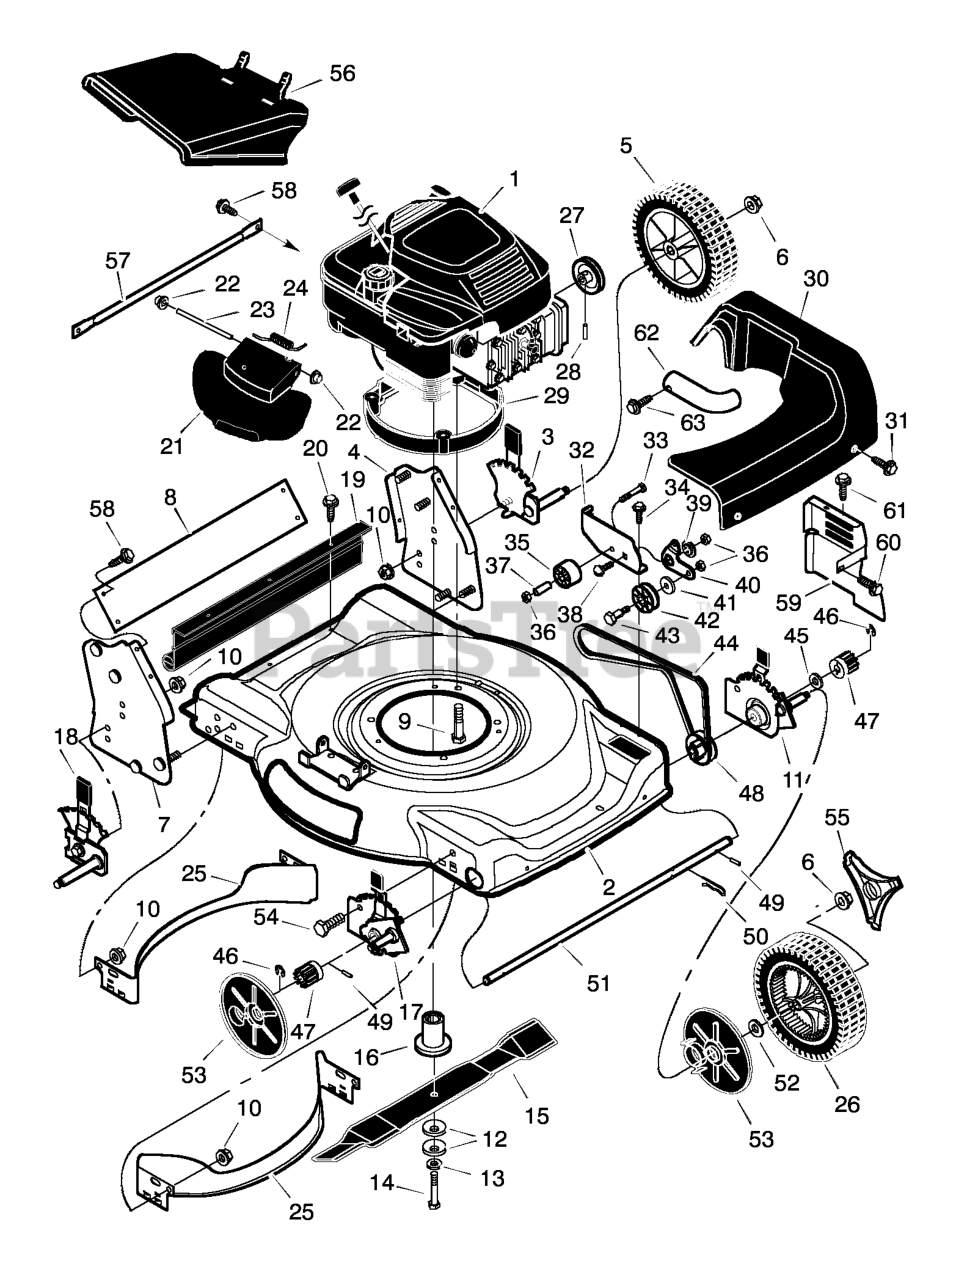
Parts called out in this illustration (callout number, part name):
1	Engine
2	Housing
3	Height Adjuster, Left Rear
4	Bracket, Left Handle
5	Wheel and Tire, Rear
6	Locknut, Flange
7	Bracket, Right Handle
8	Brace, Handle Bracket
9	Bolt, Engine
10	Nut
11	Height Adjuster, Left Front
12	Washer, Belleville
14	Bolt, Hex
16	Adapter, Blade
17	Height Adjuster, Right Front
18	Height Adjuster, Right Rear
19	Guard, Rear
21	Cover, Mulcher
22	Push- On Cap
23	Pin, Pivot
26	Wheel and Tire, Drive
28	Pin, Spring
29	Base, Engine
30	Cover, Belt
32	Bracket, Idler Support
36	Locknut
37	Bearing
38	Bolt, Carriage
40	Arm, Idler
42	Pulley, Idler
43	Bolt, Shoulder
46	Ring, Retainer
47	Gear, Pinion
49	Pin, Drive
50	Pin, Hair
52	Washer
53	Cover, Dust
54	Bolt
55	Hub Cap
56	Deflector, Chute
59	Shield, Heat
60	Screw
62	Tube, Exhaust
